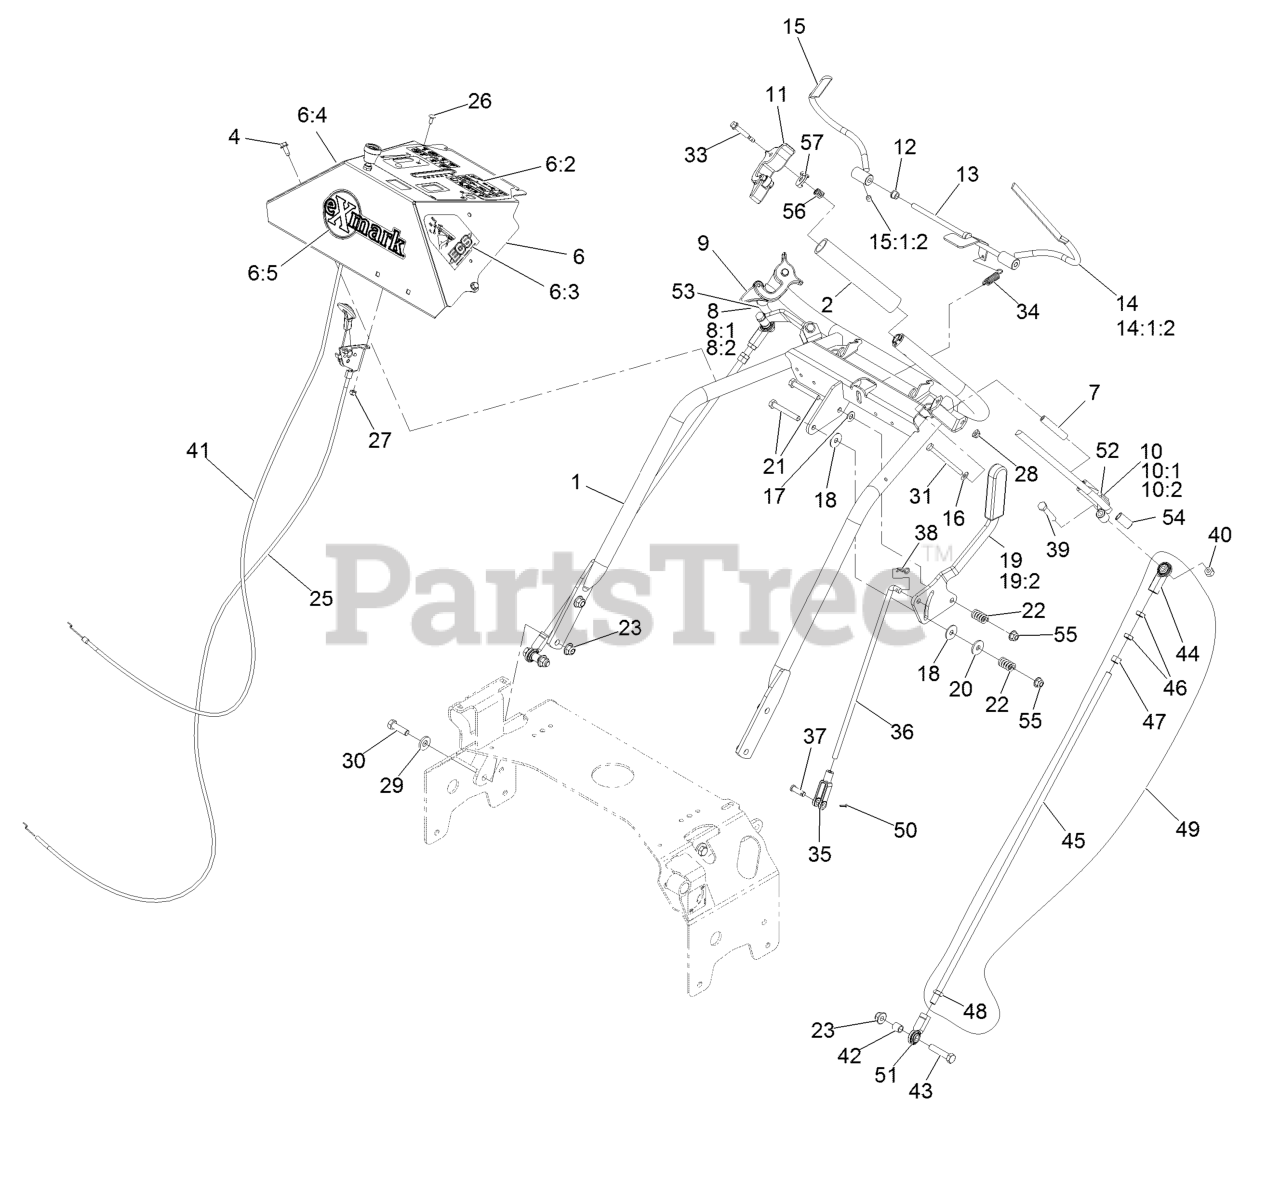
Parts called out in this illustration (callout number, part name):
1	Weld, Handle
2	Grip-Bar, Handle
4	Screw-HWH 1/4-20 X .62
6	ASM, Console W/ Decals
6:2	Decal-Console
6:3	Decal, Ecs Instruction LH
6:4	Decal, Ecs Instruction RH
6:5	Decal, Exmark Logo
7	Bushing-Lever, Drive
8	Asm, Drive Lever RH
8:1	Wld,RH Drive Lever
8:2	Bushing, Sleeve
9	Thumb Latch Asm RH
10	Asm, Drive Lever LH
10:1	Wld,LH Drive Lever
10:2	Bushing, Sleeve
11	Thumb Latch Asm LH
12	Bushing-Nylon
13	Rod Weldment, OPC
14	Wld,LH OPC Lever
14:1:2	Setscrew-5/16-24 X 5/16
15	Wld,RH OPC Lever
15:1:2	Setscrew-5/16-24 X 5/16
16	Washer-1/4 SAE
17	Washer-5/16 SAE
18	Washer-Friction
19	Lever, Shift W/Grip
19:2	Grip-Handle, Steering
20	Washer-Friction Disc
21	Screw-HH 5/16-18 X 2 1/4
22	Spring-Compression
23	Nut-Nyloc 3/8-16 Flg
25	Control-Throttle
26	Bolt-Carriage #10-24 X 1/2
27	Nut-Nyloc #10-24
28	Nut-Nyloc 1/4-20 Flg
29	Washer-Spring Disc 3/8
30	Screw-HH 3/8-16 X 1 1/4
31	Screw-HH 1/4-20 X 2 3/4
33	Screw-Shoulder
34	Spring-Extension
35	Yoke-Adjustable
36	Rod, Speed Control
37	Pin-Clevis 5/16 X 1 49/64
38	Hairpin-Cotter
39	Screw-HH 5/16-18 X 1 3/4
40	Nut-Nyloc 5/16-18
41	Cable, Choke
42	Spacer-Tube, Pump Link
43	Screw-HH 3/8-16 X 1 3/4
44	Balljoint
45	Rod,Drive Lever
46	Nut-Jam 3/8-24
47	Nut-Hex 3/8-24
48	Nut-Jam 3/8-24 LH
49	Drive Link ASM
50	Pin-Cotter 3/32 X 1/2
51	Joint-Ball End
52	Wld,LH Drive Lever
53	Wld,RH Drive Lever
54	Bushing, Sleeve
55	Nut-Nyloc 5/16-18 Flg
56	Spring-Compression
57	Latch, Ecs
